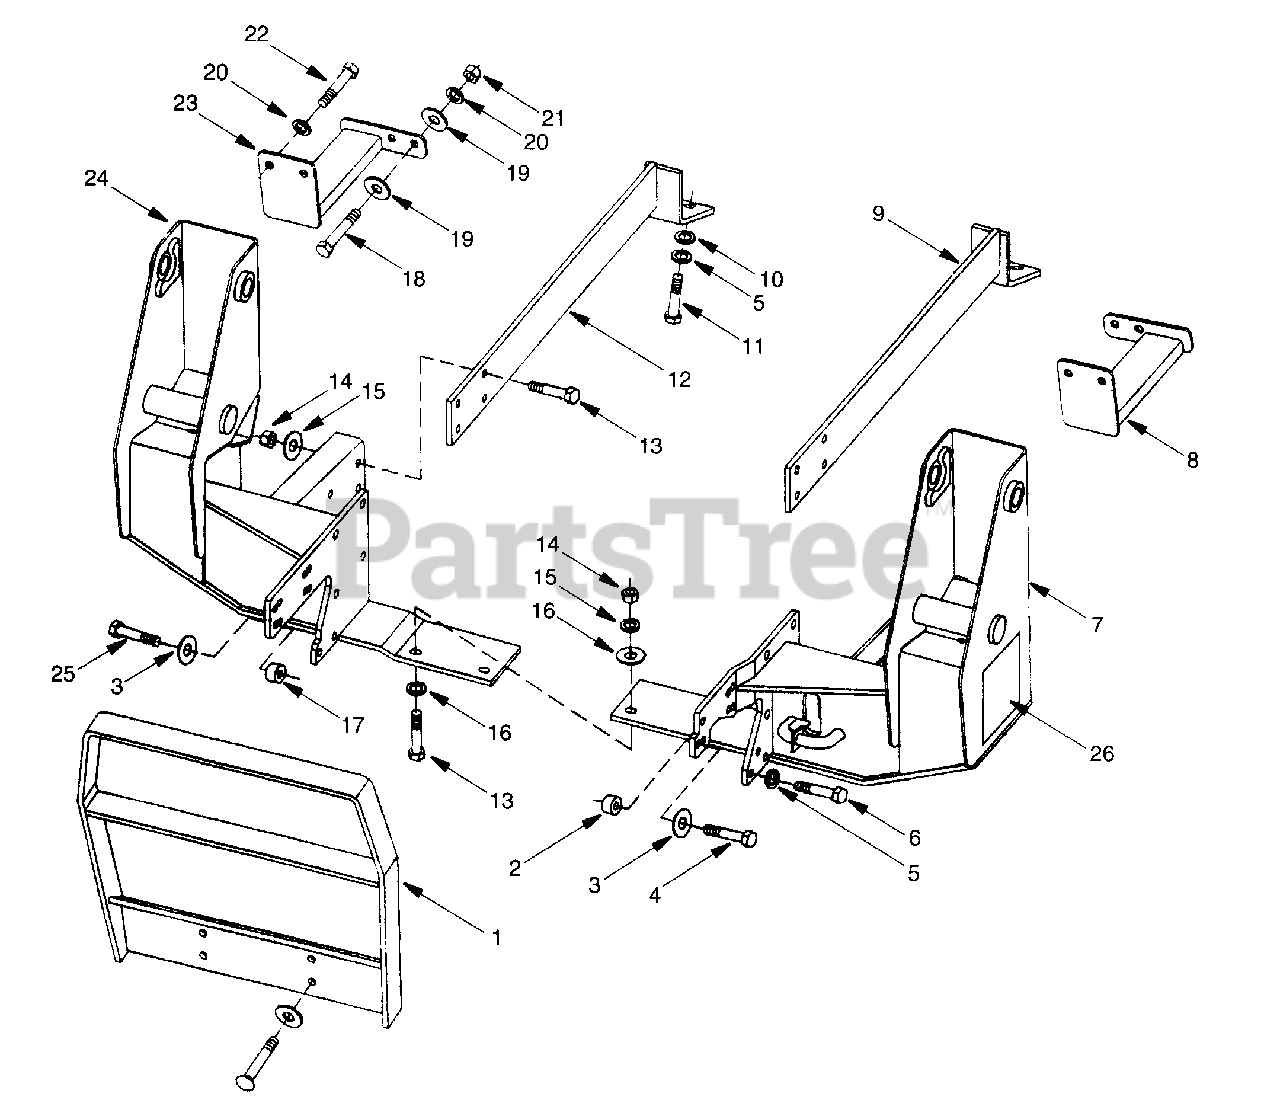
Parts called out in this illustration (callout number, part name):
1	Grille Guard
2	Spacer, 1.15 (Tractor Model 7300/05)
3	Disc Lock Washer, .515 x .937 x .13
4	Hex Hd Cap Scrw, 12mm x 1.25 x 70 (Tractor Model 7300/05)
5	Lockwasher, 9/16
6	Hex Hd Cap Scrw, 14mm x 20 x 30
7	Loader Mount, LH
9	Rear Support, LH
10	Flat Washer, 1/2 SAE
11	Hex Hd Cap Scrw, M14-2.0P x 5mm
12	Rear Support, RH
13	Hex Hd Cap Scrw, 1/2 NC x 1.5 GR5
14	Plated Hex Nut, 1/2 NC
15	Shakeproof Lockwasher, 1/2
16	Flat Washer, 1/2 SAE
17	Spacr, 1.715 (Tractor Model 7260/65)
18	Hex Hd Cap Scrw, 3/8 NC x 1 GR5
19	Washer, 3/8
20	Lockwasher, 3/8
21	Plated Hex Nut, 3/8 NC
22	Self Tapping Screw, Type T .38 x 1.25
24	Loader Mount, RH
25	Hex Hd Cap Scrw, 12mm x 1.25 x 100 (Tractor Model 7260/65)
26	Loader Mounting Label
